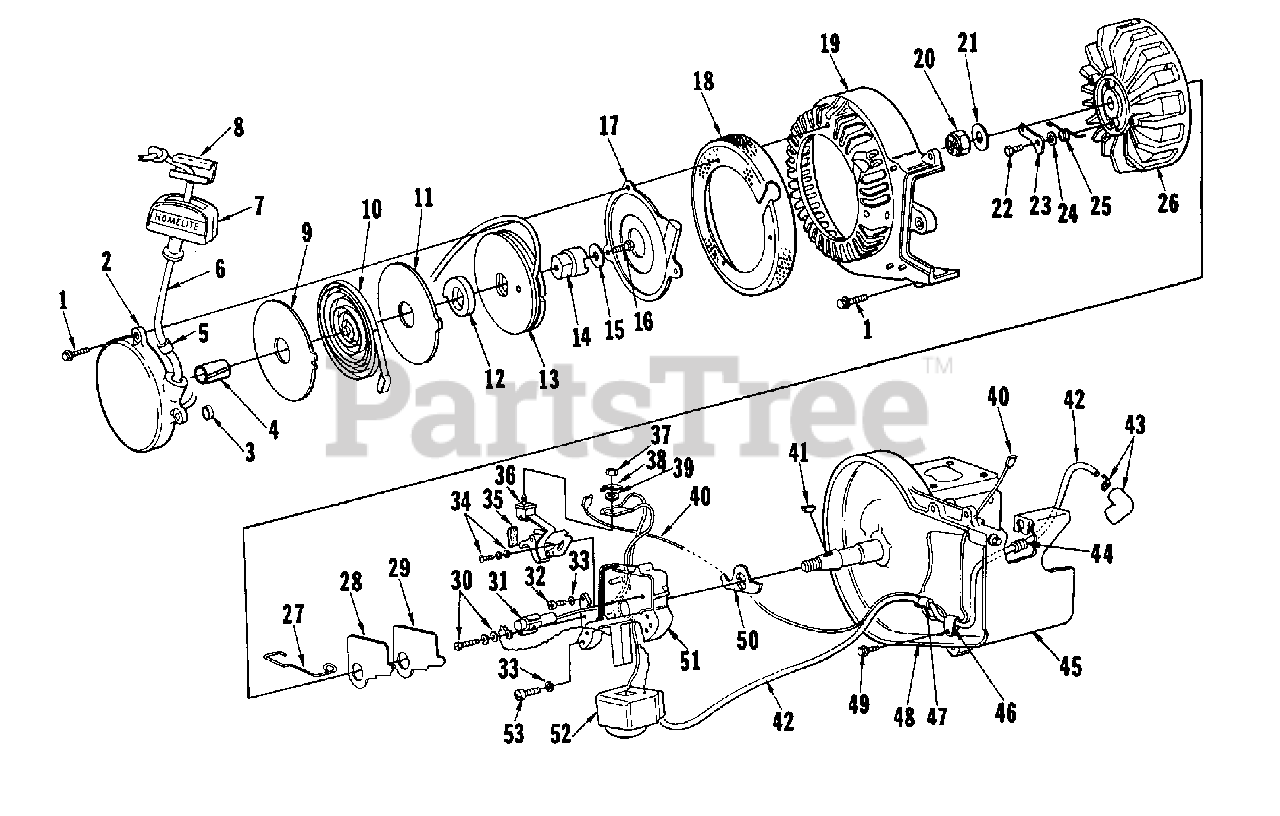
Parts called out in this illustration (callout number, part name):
1	SCREW- Hex, 12-24 x 3/4
2	COVER- Starter
3	BUSHING- Spring outer loop
4	BUSHING- Starter post
5	BUSHING- Starter rope
6	ROPE- Starter, 48" #5
7	GRIP- Rope
8	INSERT- Rope retaining
9	SHIELD- Spring (inner)
10	SPRING- Rewind
11	SHIELD- Spring (outer)
12	LOCK- Rewind spring
13	PULLEY- Starter
14	CUP- Starter
15	WASHER- Retaining
16	SCREW- Hex, 10-32 x 1/2
17	SHIELD- Sawdust
18	SCREEN- Fan housing
19	HOUSING- Fan
20	NUT- Lock, 7/16-20
21	WASHER- Flat
22	STUD- Shoulder
23	PAWL- Starter
24	WASHER- Lock, #12
25	SPRING- Starter pawl
27	CLAMP- Breaker box cover
28	COVER- Breaker box
29	GASKET- Breaker box
30	SCREW GROUP- Condenser
31	CONDENSER- W/terminal
32	SCREW- Fil. 10-24 x 1/2
33	WASHER- Lock, #10
34	SCREW GROUP- Point
35	POINT SET
37	NUT- Terminal
38	TAB- Ground
39	WASHER- Terminal
40	LEAD- Ground w/terminals
41	KEY- Rotor
42	LEAD- High tension
43	TERMINAL- Spark plug
44	GROMMET
45	SHIELD- Cylinder
46	CLAMP- Lead
47	SLEEVE- Insulating
48	CRANKCASE- W/pin (See Fig 2)
49	SCREW- Hex 10-32 x 3/8
50	SEAL Breaker box
51	BOX- Breaker w/core
52	COIL- W/ground terminal
53	SCREW- Fil, 10-24 x 7/8
